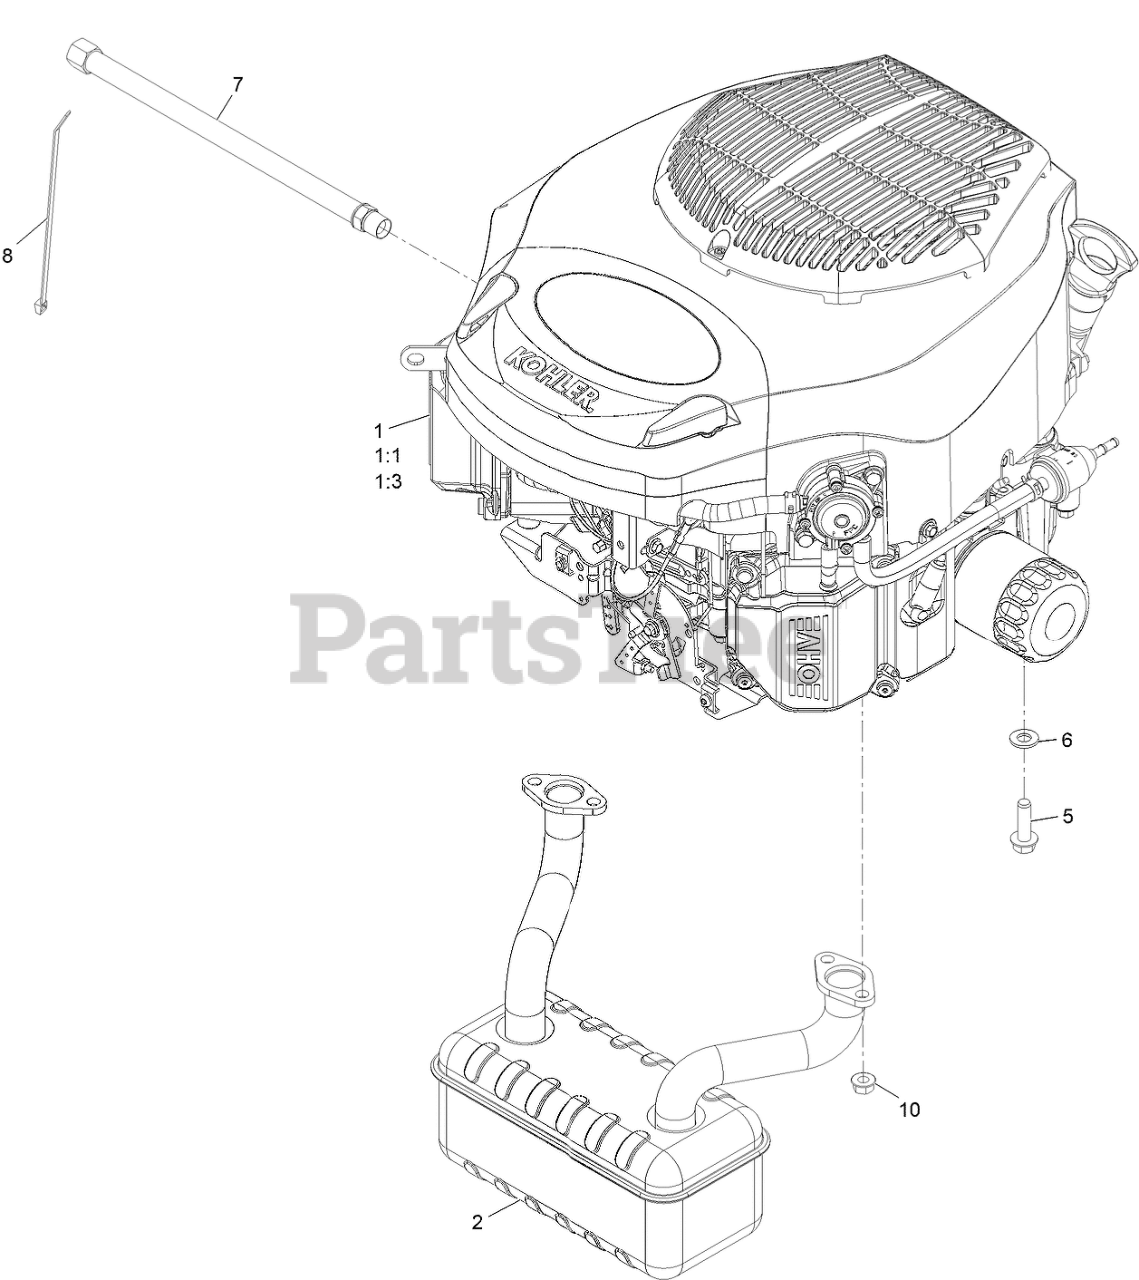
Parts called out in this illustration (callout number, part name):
1:1	GASKET-EXHAUST
1:3	PLUG-PIPE, SQH
2	MUFFLER
5	SCREW-THD
6	WASHER-FLAT
7	HOSE-DRAIN, OIL
8	TIE-CABLE
